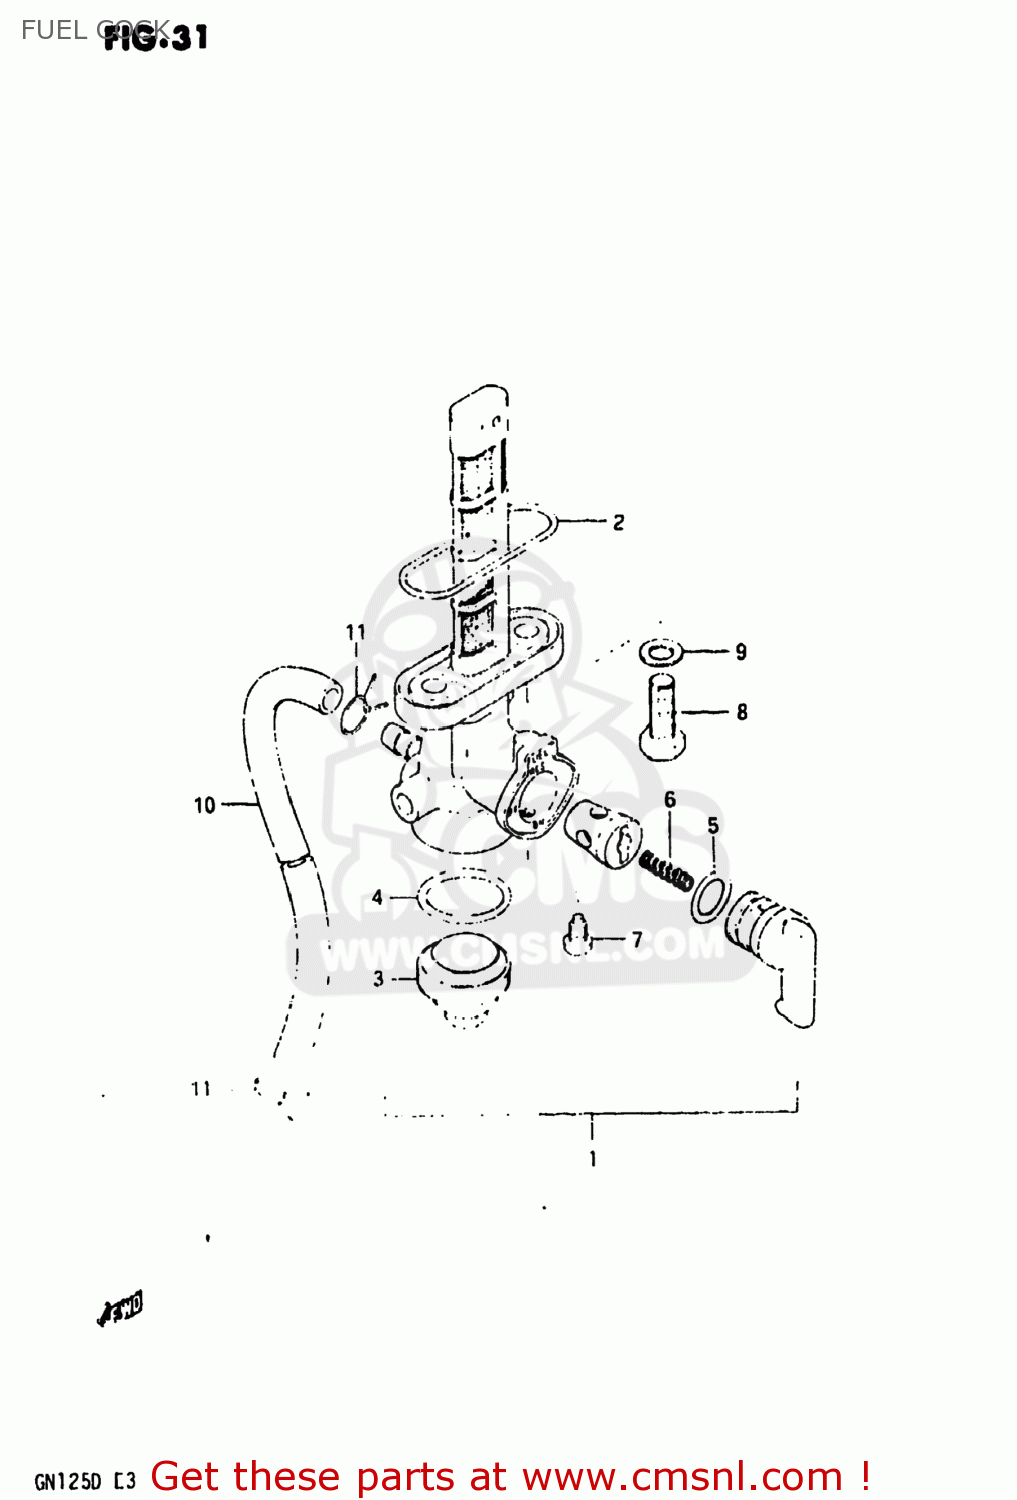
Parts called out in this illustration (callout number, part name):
1	COCK ASSEMBLY,FUEL
2	O RING,FUEL COCK
3	CUP,STRAINER
4	GASKET,FILTER (NAS)
5	O-RING
6	SPRING
7	SCREW
8	BOLT(6X20)
9	GASKET
10	HOSE
11	CLIP
